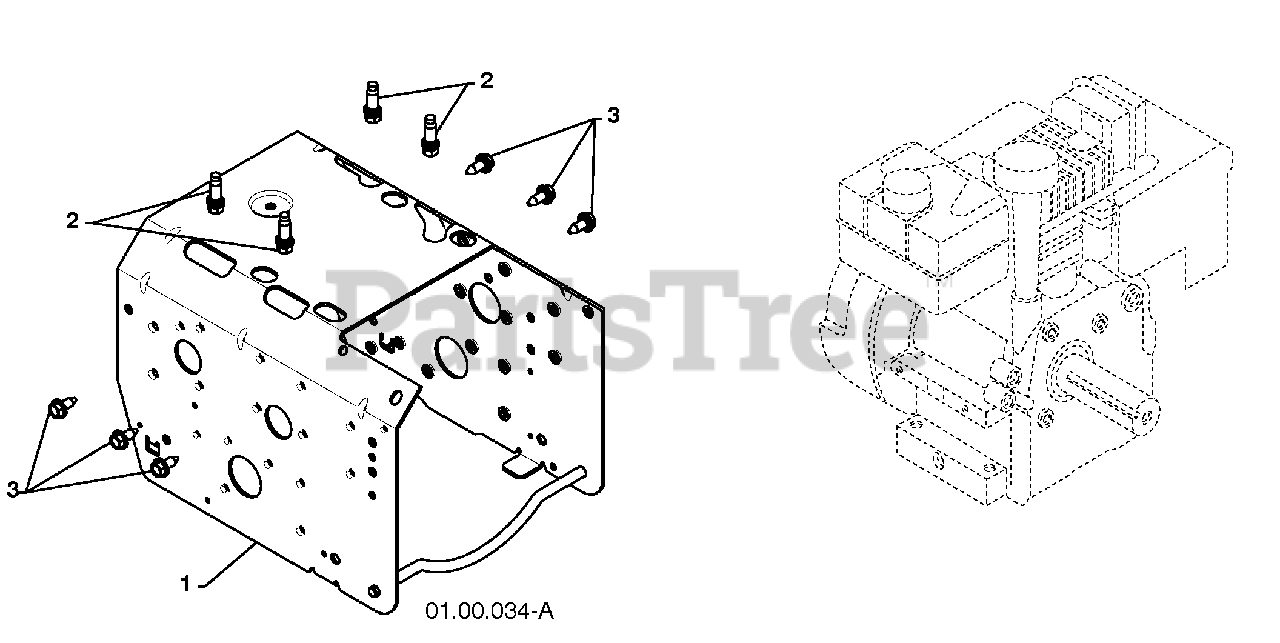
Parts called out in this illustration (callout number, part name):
1	FRAME
2	BOLT 3/8-16
3	SCREW 5/16-18 X .750
